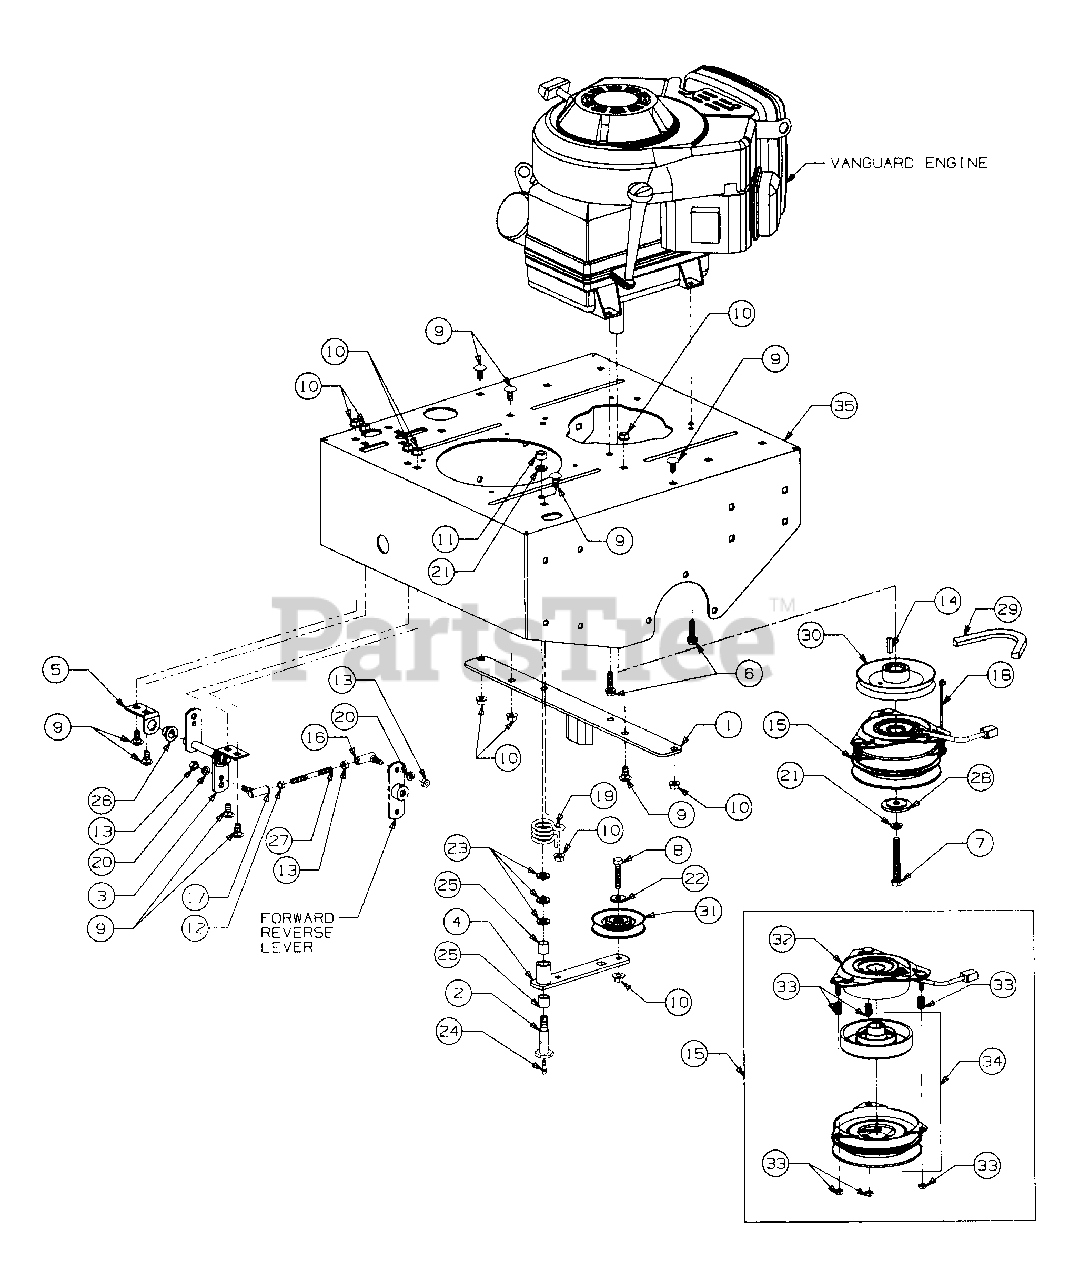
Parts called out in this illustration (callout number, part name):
3	Lever, F/R Control
4	Arm Assy, Idler
5	Bracket, Lever Angle
6	Screw, Hex L-Wash Tapp, 3/8-16 X 1.25 Lg
7	Screw, Hex Cap, 7/16-20 X 3.0 Lg GR5
8	Screw, Hex Cap, 3/8-16 X 1.75 Lg
9	Bolt, Sht Nk Carriage, 3/8-16 X .75 Lg GR5
10	Nut, Hex Flanged Lock, 3/8-16
11	Nut, Hex, 7/16-14 GR5
12	Nut, Hex Jam, 5/16-24 LH Thread
13	Nut, Hex, 5/16-24 GR5
14	Key, Square, 1/4 X 1.0 Lg
15	Clutch Assy, PTO
16	Ball Joint, 5/16-24
17	Ball Joint, 5/16-24 LH Thread
18	Cable Tie
19	Spring, Torsion
20	Washer, Lock, 5/16
21	Washer, Lock, 7/16
22	Washer, Special, .378 X 1.00 X .125 Thk
23	Washer, Flat, .469 X .875 X .105 Thk
24	Fitting, Lube
25	Bearing, Sleeve
26	Bearing, Hex Flange
27	Rod, Control
28	Spacer, Clutch
29	Belt, Transmission, 1/2 X 40.0 Lg
30	Pulley, Engine
31	Pulley, V-ldler
32	Field
33	Mounting Accessories
34	Kit, Rotor & Armature Assy
35	Deck w/Graphic, Engine Mtg
